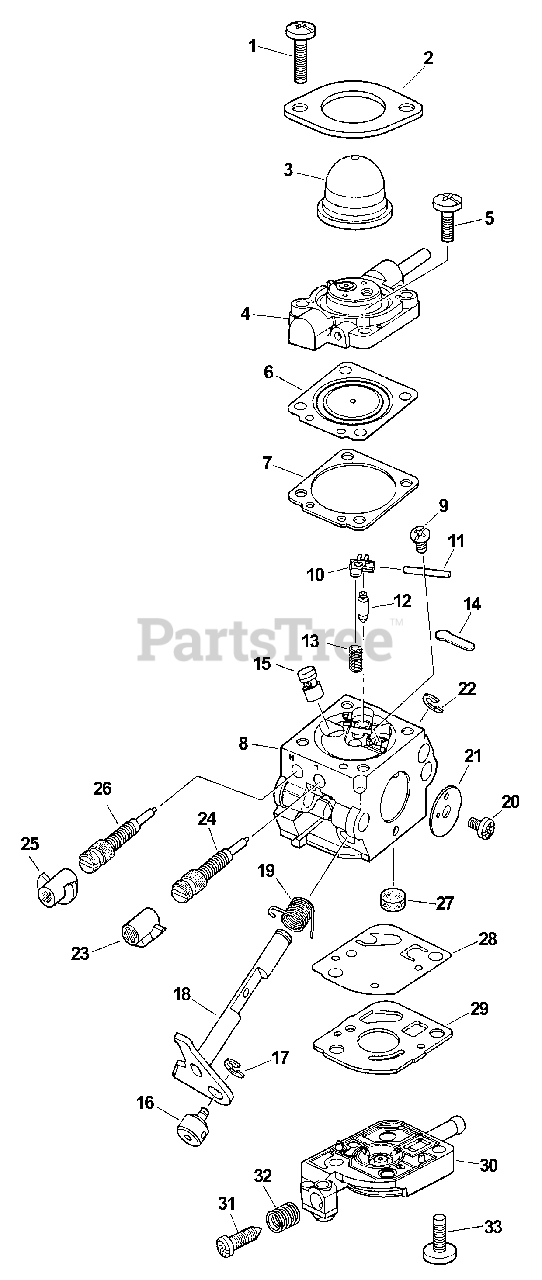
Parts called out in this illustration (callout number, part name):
1	SCREW, RETAINER
2	RETAINER, PURGE BULB
3	BULB, PURGE
4	BASE, PURGE
5	SCREW, PURGE BASE
6	DIAPHRAGM, METERING
7	GASKET, METERING
8	BODY, CARBURETOR
9	SCREW, METERING LEVER PIN
10	LEVER, METERING
11	PIN, METERING LEVER
12	VALVE, INLET NEEDLE
13	SPRING, METERING LEVER
14	PLUG, WELCH
15	NOZZLE, CHECK VALVE
17	RING, RETAINING
18	SHAFT, THROTTLE
19	SPRING, RETURN
21	VALVE, THROTTLE
22	RING, RETAINING
23	CAP, LIMITER
24	NEEDLE - LOW SPEED
25	CAP, LIMITER
26	NEEDLE - HIGH SPEED
27	STRAINER
28	DIAPHRAGM, PURGE
29	GASKET, PURGE
30	BASE, PURGE
31	SCREW, IDLE ADJUST
32	SPRING, IDLE ADJUST
33	SCREW, PUMP COVER
